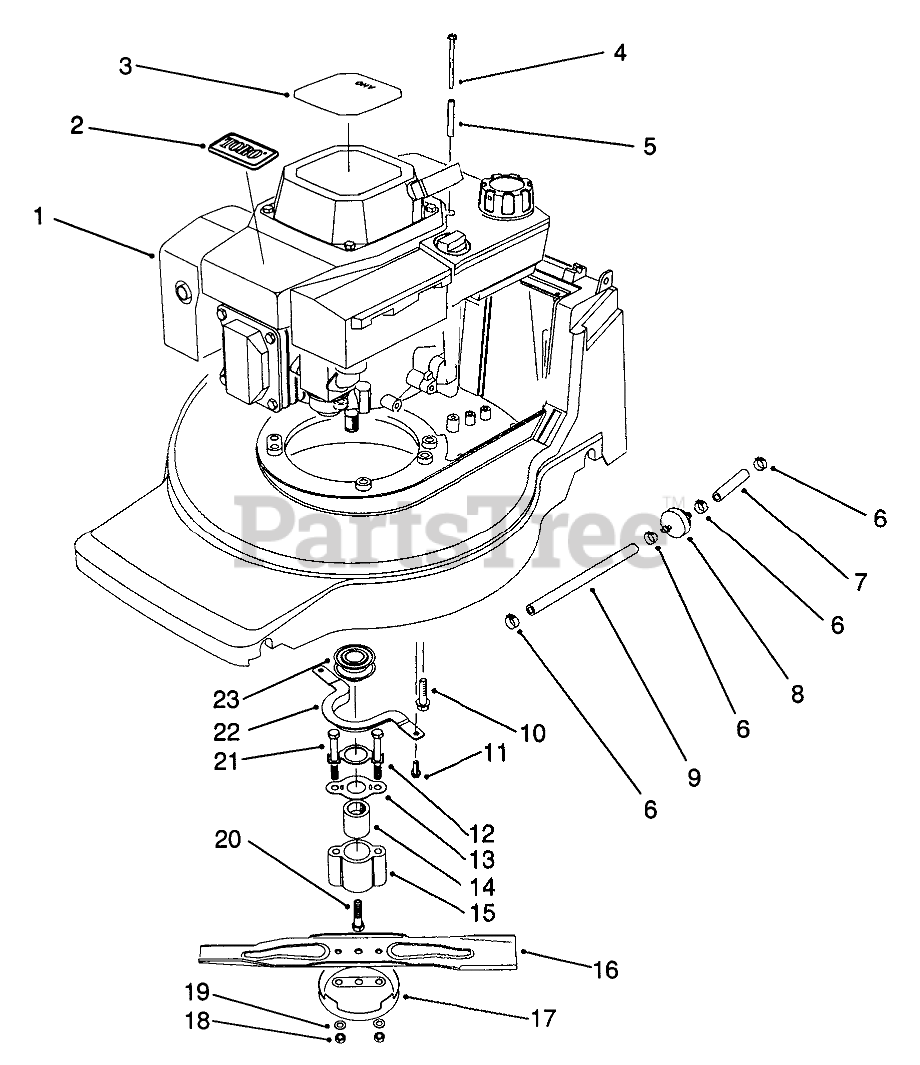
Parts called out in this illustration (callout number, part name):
1	Engine-OHV
2	TORO LOGO PLT
3	DECAL-HV INT'L
4	THRD FORMING SCREW
5	TUBULAR SPACER
6	CLAMP-FUEL LINE
7	LINE-GAS
8	FILTER-FUEL
9	HOSE-FUEL
10	SCREW-HWHTF
11	SCREW-HWH
12	BLADE RETAINER BRKT
13	SPRING FRICTION
15	RETAINER
16	Blade-48cm
17	CUP-SCALP, ANTI
18	NUT-LOCK
19	WASHER
20	SCREW - CRANKSHAFT
21	SCREW - BLADE
22	Guide-Belt
23	PULLEY-DRIVE, ZONE START
